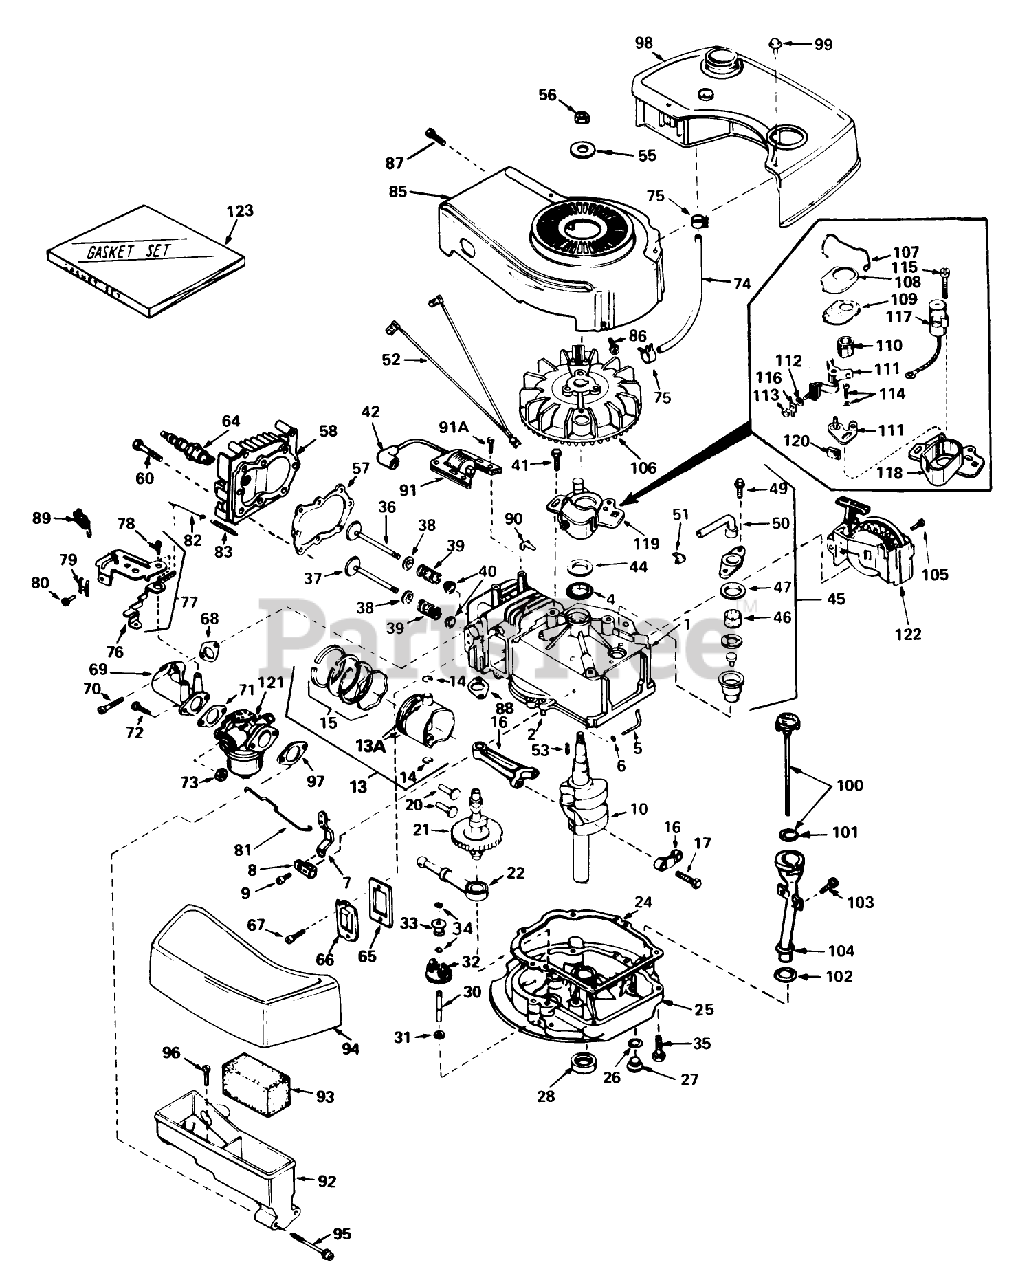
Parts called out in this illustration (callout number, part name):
1	Cyiinder Assy. (Incl. Ref. #2, 4 105)
2	Pin-Dowel
4	Seal-Oil
5	Rod, Governor (Incl. No. 36)
6	Washer-Flat
7	Governor Lever
8	Clamp-Lever, Governor
9	Screw
10	Crankshaft
13	Piston, Pin Ring Assy. (Std.)(Incl. Ref. #13A, 14 15)
13	Piston,Pin Ring Assy. (.010 over-size)(Incl. Ref. #13A, 14 15)
13	Piston, Pin Ring Assy. (Incl. Nos. 13A, 14 15)(.020 oversize)
13A	Piston Pin Assy. (Incl . Ref. . #14) (Std.)
13A	Piston Pin Assy. (Incl. Ref. #14) (.010 Oversize)
13A	Piston Pin Assy. (.020 oversize) (Incl. Ref. #14)
14	Ring-Retaining, Piston Pin
15	Ring Set Piston (Std.)
15	Ring Set Piston (.010 Oversize)
15	Ring Set Piston (.020 Oversize)
16	Rod Assy., Connecting (Incl. Ref. #17)
17	Bolt-Rod, Connecting
20	Lifter-Valve
21	Camshaft(Mech.Comp. Release)
22	Oil Pump ASM
24	Gasket, Mounting
25	Flange Assy., Mounting (Incl. Ref. #26thru 30)
26	Gasket-Oil Drain
27	Plug Oil Drain
28	Seal Oil
30	Shaft-Governor
31	Washer-Flat
32	Governor Gear ASM
33	Spool-Governor
34	Ring-Retaining
35	Screw (1/4-20 x 1-1/4)
36	Valve, Intake (Incl. Ref. #38, 39 40) (Std.)
36	Valve, Exhaust (1/32" Oversize) (Incl. Nos. 8, 9 10)
37	Valve, Exhaust (Standard) (Incl. Nos. 8, 9 10)
37	Valve, Exhaust (1/32" Oversize) (Incl. Nos. 8, 9 10)
38	Cap-Upper Valve Spring
39	Spring-Valve
40	Cap-Valve, Spring
41	Screw
42	Cover-Spark Plug
44	Gasket Stator
45	Breather Assy. (Incl. Ref. #46, 47, 49, 50 51 )
46	Element-Breather
47	Gasket-Breather
49	Screw (10-24 x 9/16)
50	Tube, Breaker
51	Clip, Breather
52	Wire Ground
53	682488 LB GRASS HI-
55	Washer-Belleville
56	Nut-Flywheel
57	63573 GIL 42 SNWTHW
58	Head-Cylinder
60	Screw (5/16-18x1-1/2)
64	Plug, Spark (J17LM or equiv.)
64	Plug, Spark (Champion RCJ-8)
65	Gasket-Breather
66	Cover-Valve
67	Screw
68	Gasket, Intake
69	Pipe, Intake
70	Screw (1/4-20 x 1)
71	Gasket-Carburetor
73	Nut and Lock Washer (1/4-28)
74	Line-Fuel
75	Clamp-Line, Fuel
76	Lever Control
77	Control Assy., Speed (Incl. Nos, 76, 78 89)
78	Screw, Hex Washer Hd Shoulder Self-Tap
79	Conduit
80	Screw (10-32 x 3/8)
81	Link-Throttle
82	Link Governor Spring
83	Spring Governor
85	Housing Blower
86	Screw
87	Screw (10-24 x 9/16)
88	Gasket Exhaust
89	Terminal
90	Clip-Wire
91	Lamination Coil Assy. (Incl. No. 42)
91A	Screw
92	Body Air Cleaner
93	Filer, Air
94	Cove, Air Cleaner
95	Screw Fil Hd.
96	Screw, Hex Hd.
97	Gasket-Air Cleaner
98	Tank, Fuel
99	Screw (10-32 x 35/64)
100	Dipstick, Oil (Incl. Ref. #101)(Twist Lock)
101	O-Ring
102	Gasket
103	Screw (10-32 x 1/2)
104	Tube-Oil Fill
105	Screw (1/4-20 x 1/2)
106	FIywheel
107	Spring Breaker Box
108	Cover-Dust
109	Gasket-Dust Cover
110	Cam-Breaker
111	Breaker Assy.
112	Washer
113	DECAL
114	Breaker Screw
115	Condenser Screw
116	Terminal, Ground
117	Condenser
118	Stator Plate
119	Stator Plate Assy. (incl. Nos. 107, 111 thru 118 120)
120	Felt,Cam Wiper
121	Carburetor (Incl. Ref. #71 )
122	Starter, Side Mount
123	53024/VAR.16HP O/P
